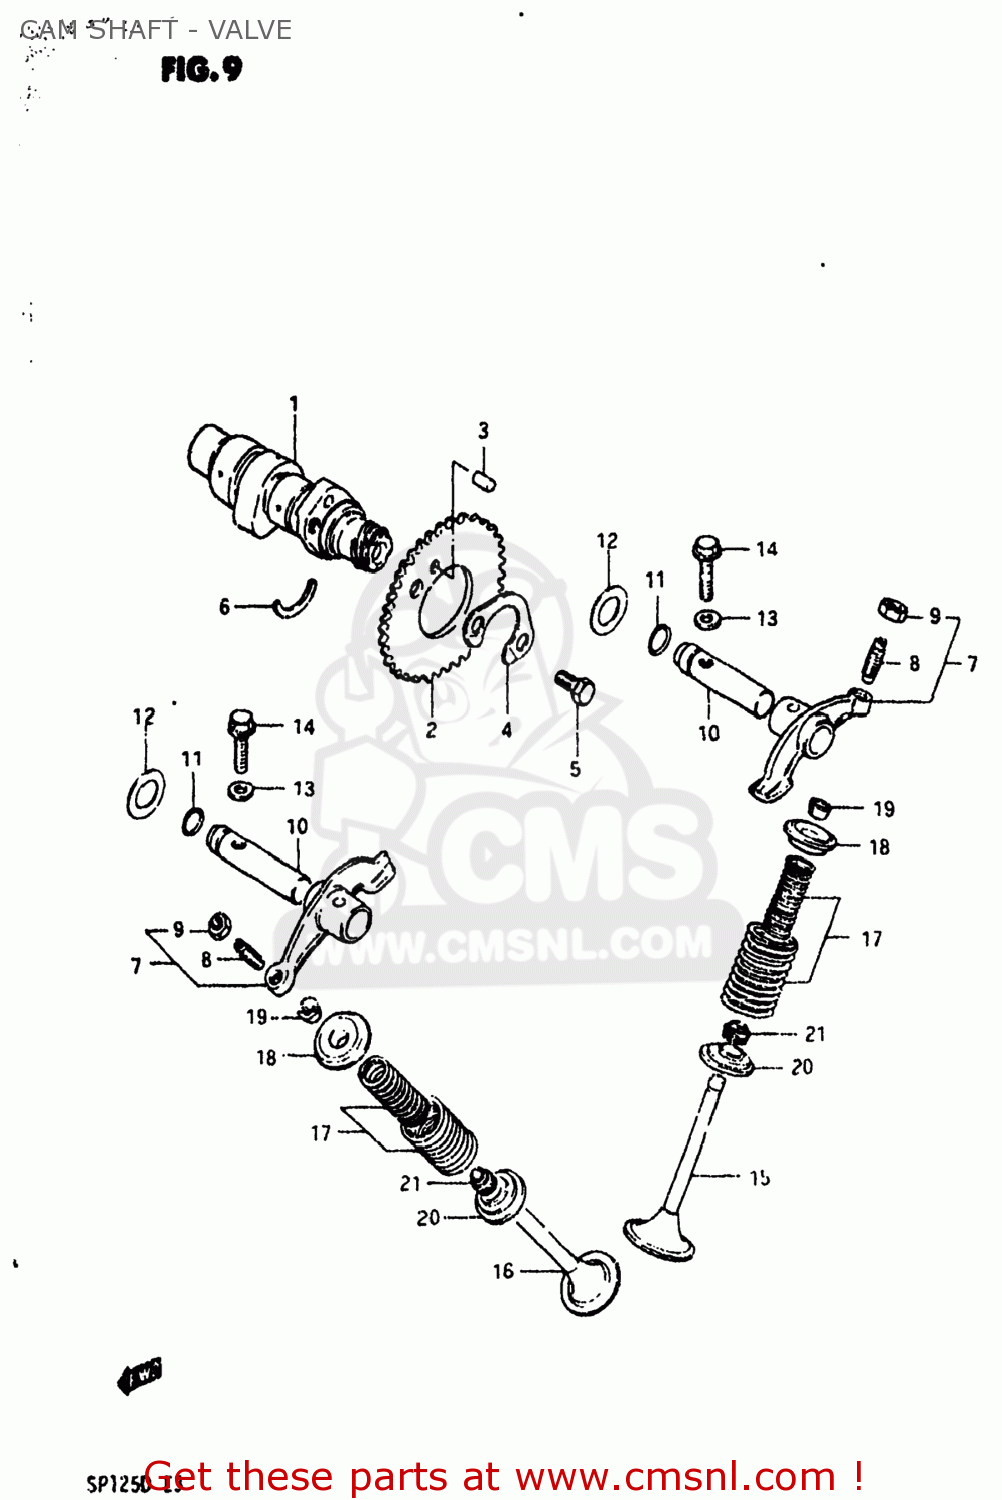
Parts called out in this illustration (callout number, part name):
1	CAMSHAFT
2	SPROCKET,CAMSHAFT
3	PIN(5X8)
4	WASHER,SPROCKET
5	BOLT(6X10.5)
6	C RING
7	ARM,VALVE ROCKER
8	SCREW,TAPPET ADJUSTING
9	NUT,ADJUSTING SCREW
10	SHAFT,VALVE ROCKER
11	O-RING
12	WASHER
13	GASKET(6.2X11X1).2 (NAS)
14	BOLT
15	VALVE,INTAKE
16	VALVE,EXHAUST
17	SPRING SET,VALVE
18	RETAINER,VALVE SPRING
19	COTTER VALVE
20	SEAT,VALVE SPRING
21	OIL SEAL
